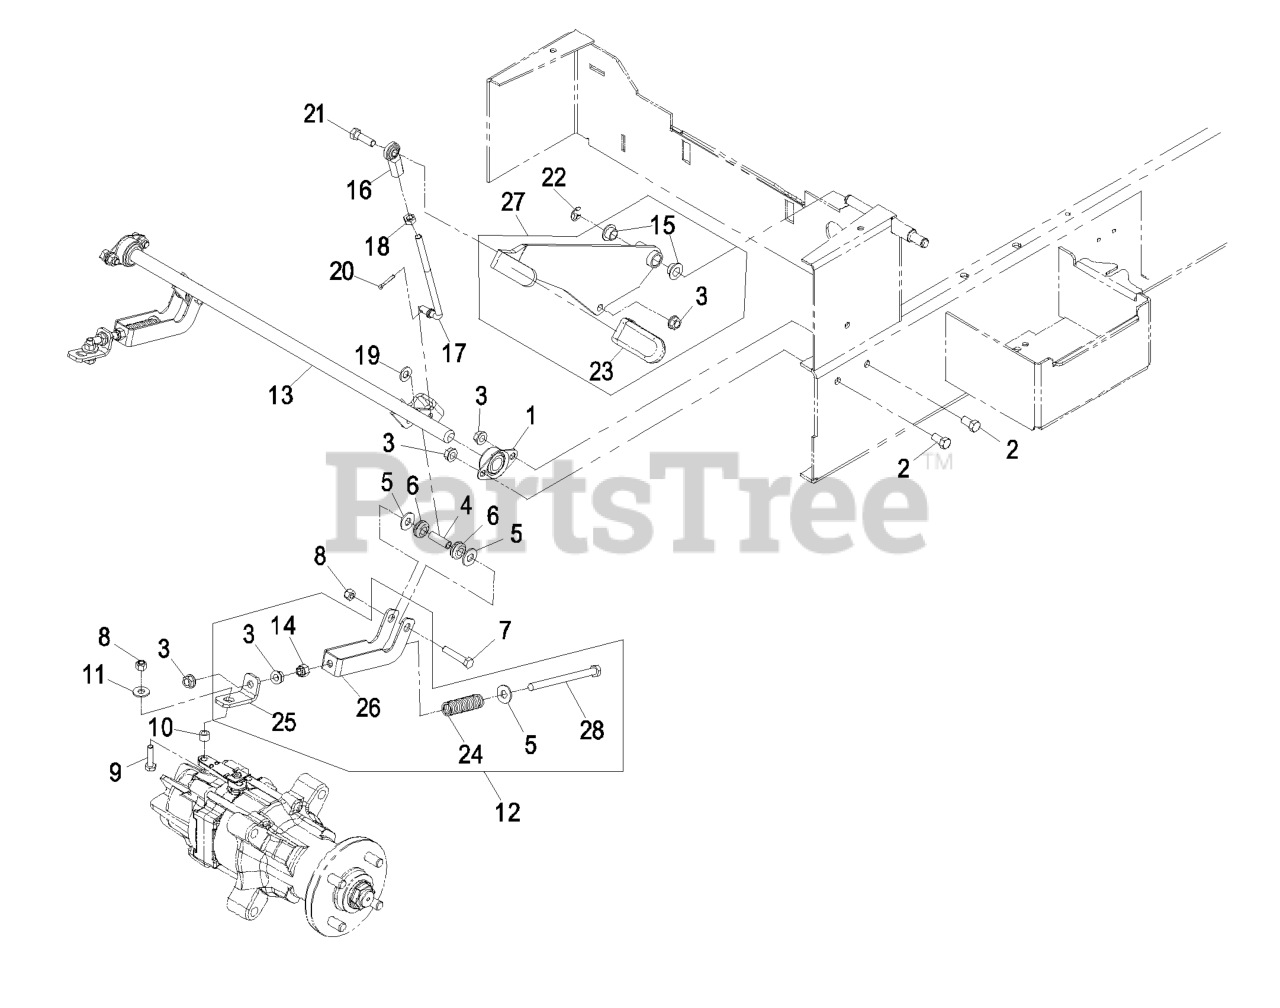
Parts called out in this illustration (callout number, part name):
1	BEARING-FLANGE, SIDE
2	SCREW-HH
3	NUT-HHF, WHIZ
4	SPACER,.438 OD X 1.312 (P
5	WASHER-FLAT
6	GROMMET
7	SCREW-HH
8	NUT-LOCK, NI
9	SCREW-HH
10	BUSHING, LOCATOR
11	WASHER-FLAT
12	ASM,BRAKE LINKAGE
13	WLD,BRAKE CROSS SHAFT
15	BEARING-CONTROL
16	JOINT-BALL, END
17	ROD,LINKAGE BRAKE (PLATED
18	NUT-HEX
19	WASHER-FLAT
20	PIN-COTTER
21	SCREW-HH
22	RING-RETAINING, EXTERNAL
23	GRIP-LEVER
24	SPRING,COMPRESSION
25	LINK,BRAKE (PLATED)
26	CLEVIS,BRAKE (PLATED)
27	ASM,BRAKE LEVER W/GRIP
28	SCREW-HH
